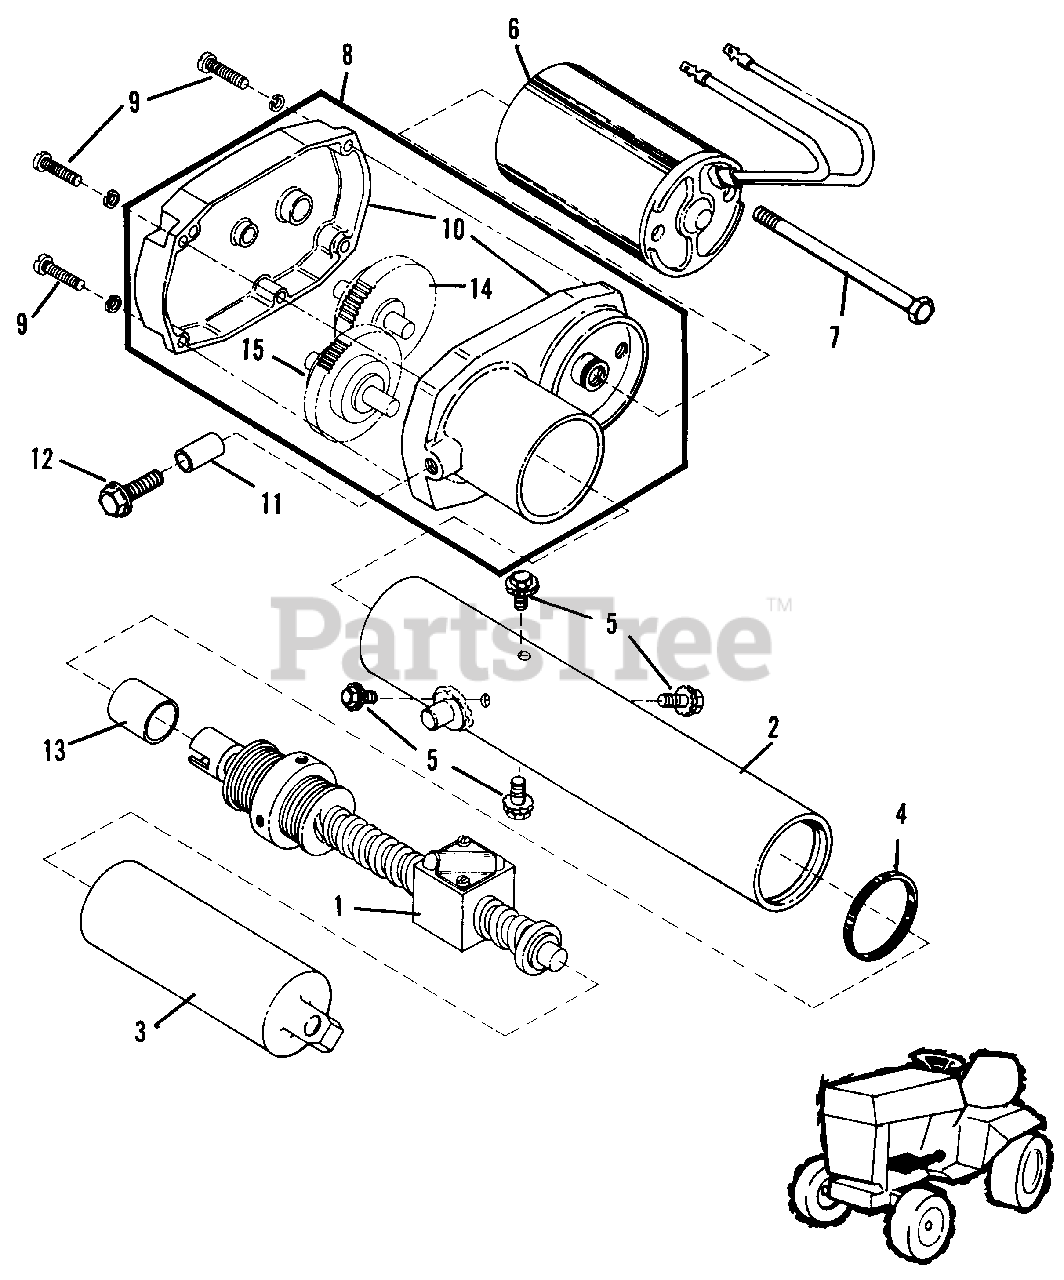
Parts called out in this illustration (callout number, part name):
1	Screw & Brake Assy.
2	Tube Assy., Outer
3	Tube Assy., Inner
4	Seal, Quad. Ring
5	Screw, Thread Cutting
7	Screw, Motor
8	Gear Box Assy.
9	Screw, Filister Hd. 10-32
12	Screw-Thread Forming
13	Sleeve-Coupling
14	Gear Assy.
15	Gear Assy.
